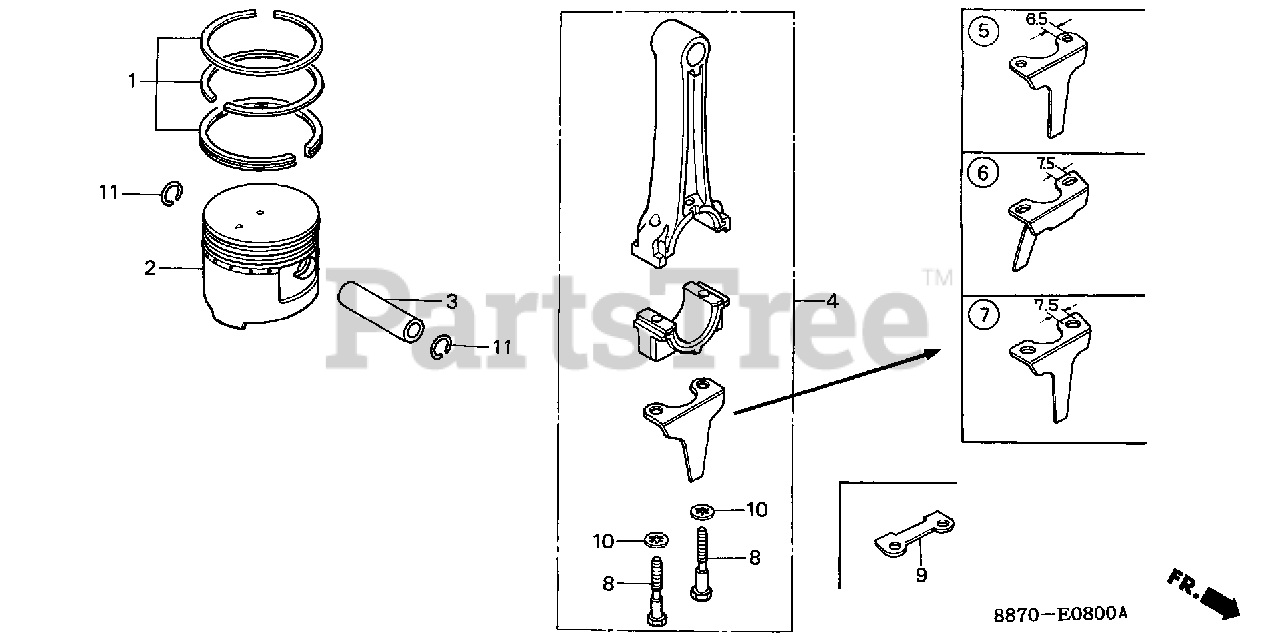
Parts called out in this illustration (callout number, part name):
1	RING SET, PISTON (STD)
1	RING SET, PISTON (0.25)
1	RING SET, PISTON (0.50)
1	RING SET, PISTON (0.75)
2	PISTON (STD)
2	PISTON (0.25)
2	PISTON (0.50)
2	PISTON (0.75)
3	PIN, PISTON
4	ROD ASSY., CONNECTING
4	ROD ASSY., CONNECTING (UNDER SIZE)
4	ROD ASSY., CONNECTING Use up to Engine SN 1229777.
4	ROD ASSY., CONNECTING Use from Engine SN 1229778.
5	DIPPER, CONNECTING ROD (NOT AVAILABLE)
6	DIPPER, CONNECTING ROD
7	DIPPER, CONNECTING ROD
8	BOLT, CONNECTING ROD (6MM)
8	BOLT, CONNECTING ROD (6MM) (NOT AVAILABLE)
8	BOLT, CONNECTING ROD (7MM)
9	WASHER B, CONNECTING ROD
10	WASHER, LOCK (6MM) (N/A: SEE ASSEMBLY)
10	WASHER, LOCK (7MM)
11	CLIP, PISTON PIN (15MM)
